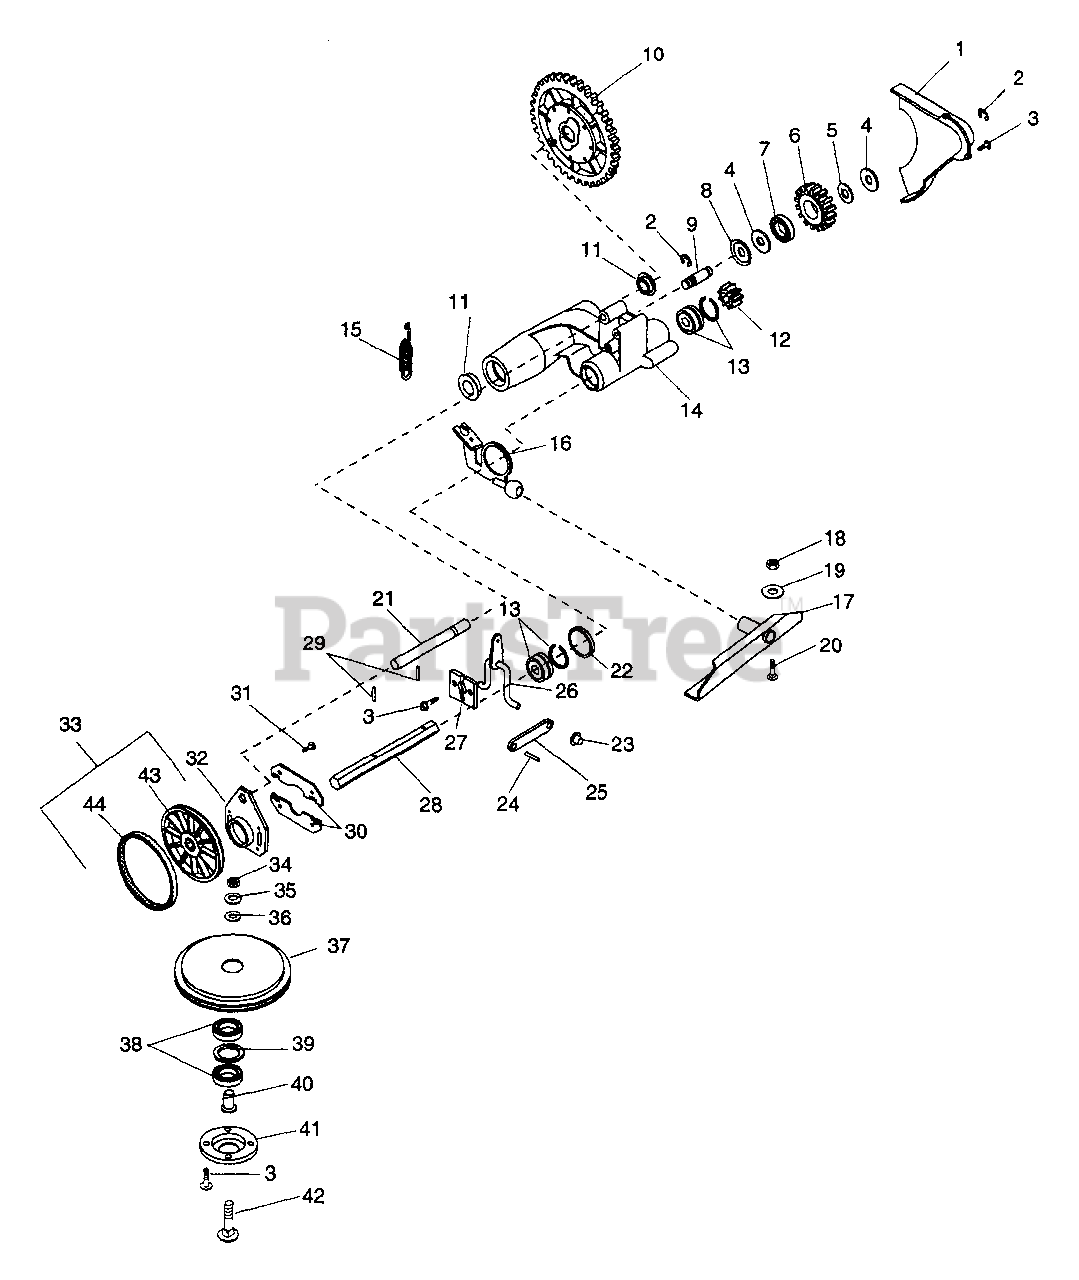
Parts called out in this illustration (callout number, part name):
1	GEAR COVER
2	RG-RTNG-EXT .438X.035
3	SCR-TAP 12-24X.50 HWH PL TR
4	WSHR-FL-STL .520X.827X.062 YZ
5	WSHR-FL-STL .505X.880X.072 PL
6	IDLER GEAR
7	BRG-BALL .500X1.375X.437
8	RETAINER
9	IDLER SHAFT
10	DIFFERENTIAL ASSEMBLY
11	BRG-BALL .625X1.378X.44
13	BRG-BALL .562X1.38X.44
14	DRIVE MOUNT
15	SG-TENS .051X.60X2.25 WLD 7.0
16	DRIVE ACTUATOR WELDMENT
17	PIVOT CHANNEL WELDMENT
18	NUT-LK .312-18 GR A PL
19	WSHR-FL-STL.344X.688X.065PL
20	BLT-RDHDSQNK .312-18X.62SHTPL
21	ROD - GUIDE
22	WSHR-FL-STL 1.390X2.00X.020 PL
23	PUSH NUT, .25
24	PIN-ROLL .125X.50
25	SHIFT LINK
26	SHIFT ARM WELDMENT
27	RETAINER PLATE
28	HEX SHAFT
29	PIN-ROLL .188X.88
30	THRUST PLATE
31	SCR-TAP 10-24X.375 HWH PL TR
32	GUIDE PLATE
33	FRICTION WHEEL ASSEMBLY
34	NUT-HEX .312-18
35	WSHR-LK .312X.097 PL HVY
36	WSHR-FL-STL .328X.875X.062 PL
37	FRICTION SHEAVE
38	BRG-BALL .625X1.375X.44
39	WSHR-FL-STL 1.062X1.344X.032PL
40	SPINDLE - BEARING
41	RETAINER - BEARING
42	BLT-RDHDSQNK .31-18X1.75 PL
43	FRICTION WHEEL HUB
44	FRICTION RING
